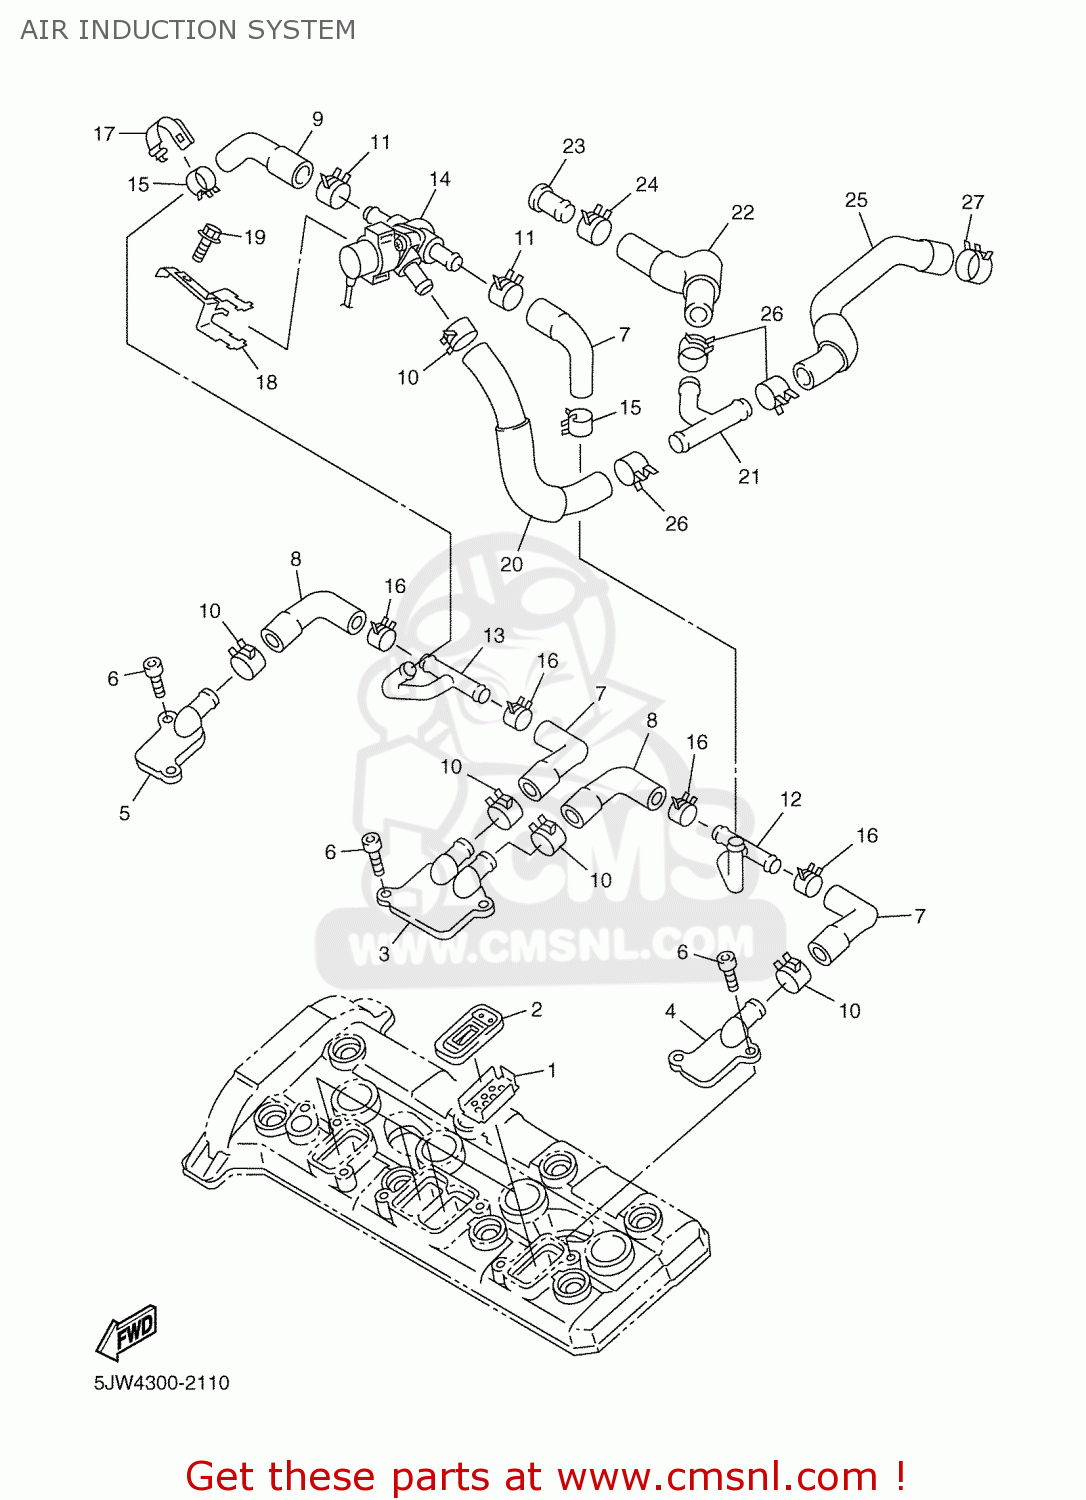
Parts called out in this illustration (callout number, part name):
01	PLATE
02	REED VALVE ASS
03	CAP, CASE
04	CAP, CASE
05	CAP, CASE
06	BOLT, HEXAGON SOCKET HEAD
07	HOSE, BEND 1
08	HOSE, BEND 2
09	HOSE, BEND 3
10	CLIP
11	CLIP
12	PIPE 1
13	PIPE 2
14	AIR CUT VALVE ASS'Y
15	CLIP
16	CLIP
17	COVER 1
18	STAY
20	HOSE, BEND 4
21	JOINT
22	PIPE 3
23	PLUG
24	CLIP
25	HOSE, BEND 5
26	CLIP
27	CLIP (4V3)
